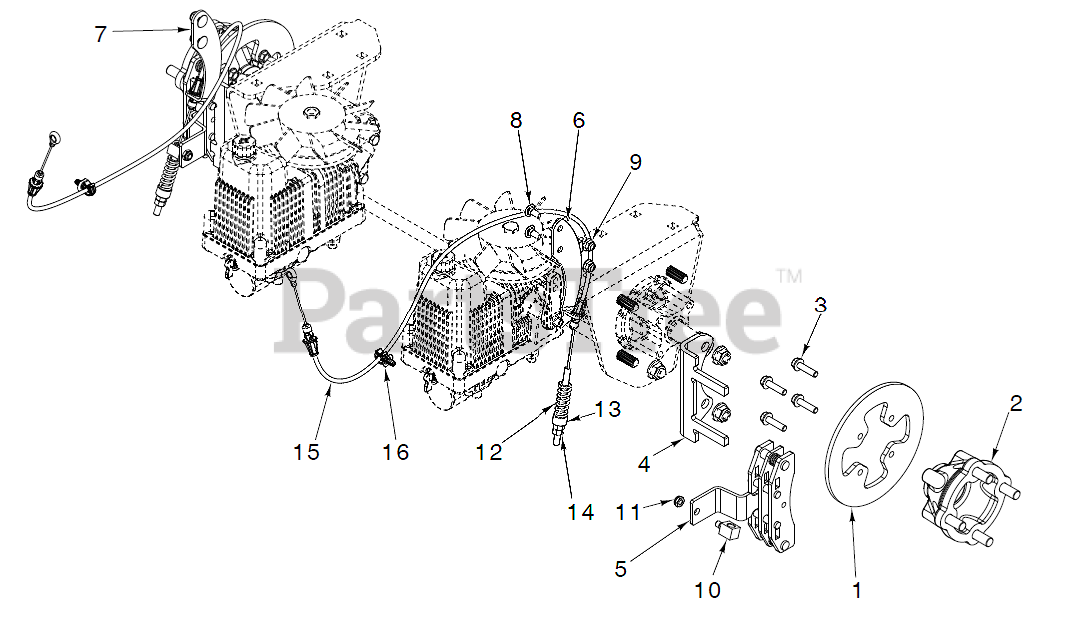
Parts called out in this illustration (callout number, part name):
2	SQUARE KEY
15	WASHER
17	SPRING.BRAKE.K46.GREEN
26	SPRING.RETURN.CRUISE
29	ROD.BRAKE.K46
35	ROD .BRAKE. PARKING. GT. HUSQ.
42	PEDAL COVER T
50	IDLER.FLAT.910.OFFSET
51	NUT LOCK FLG 3/8-16 UNC
52	IDLER.V-GROOVE.910.OFFSET
56	V-BELT.MOWER.92.40.42/K46
64	SHAFT.ASM.PEDAL.BRK.CNTR
70	CONSOLE.ASM.RH.GT.FC.HUSQ
74	SCREW.HI-LO.CONSOLE
80	STRAP.TORQUE.K46.K57R.TT
92	BOLT
99	ROD.SPRING.BYPASS.K46.LT.Z
116	NUT LOCK HEX FLANGE 5/16-18
125	SCREW
143	Screw 5/16-18 x 1/2 Hex, Self Tapping 5/16-18 x 1/2
153	RETAINER M
159	COTTER PIN
160	RETAINER CLIP
161	SPRING, RETURN LT
163	ROD.CONTROL.K57R.K46
166	NUT.PUSH.625
167	LATCH.BRAKE.SPRING
170	KEEPER.V-IDLER.CENTER.
183	SPACER AXLE
184	RB HANDLE.PARKG.BRK.HUS/PRED
186	SPACER.RETAINER
187	WASHER 12/32X2X10GA
188	RP.LINK.CLUTCH.GROUND.DRIVE
189	BELLCRANK.GROUND.DRIVE.TEX.
190	KEEPER.BELLCRANK.DRIVE
196	SCREW 3/8-16X1
197	LINK.CLUTCH.ANIT-ROTAT
206	BRKT.MOUNT.LATCH.CRUIS
207	LATCH.CONTROL.CRUISE
208	GEAR.SECTOR.CONTROL.CR
209	ROD.CONTROL.CRUISE.GT.
210	ROCKER.ASM.PEDAL.CONTR
211	BEARING.NYLON
213	KNOB.CONTROL.CRUSIE.HU
214	PEDAL.FORWARD.PAD.TEX
215	PEDAL.REVERSE.TEX.GT.4
216	BRACKET.PULLEY.IDLER.W/TEX
220	REFLECTOR.RH.TEX GT
221	RETAINER.SPRING.CLIP.H
222	WASHER 21/32 X 1-1/4 X 10 GA.
225	KEEPER.BELT.TRANSAXLE.K46
226	BRACKET.MOUNT.TORQUE.K46.TLT
227	SCREW.THDROL.5/16-18X3/4.TTY
230	WASHER.HARDENED
